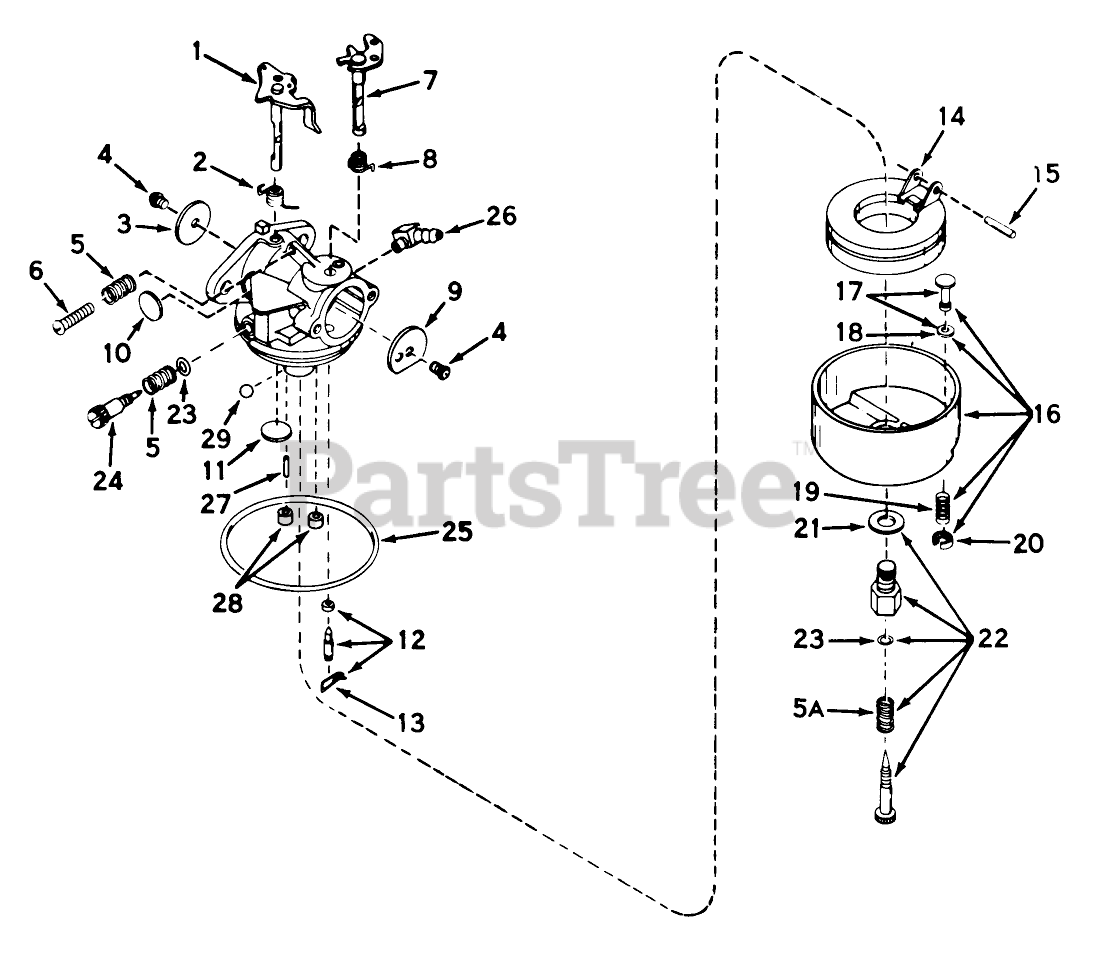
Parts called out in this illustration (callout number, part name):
1	Shaft/Lever-Throttle
2	Spring, Return
3	Shutter-Throttle
4	Screw-Shutter
5	Spring-Tension
5A	Spring
6	Screw-Throttle Crack Screw / Idle Speed
7	Shaft Lever Assy., Choke
8	Spring, Choke return
9	Shutter-Choke
10	Plug-Welch, Idle Mixture Well
11	Plug-Welch, Atmospheric Vent
12	Inlet Needle, Seat Clip Assy. (Incl. No. 13)
13	Clip-Spring
14	Float,Carburetor
15	Shaft-Float
16	Bowl Drain Assy., Float (Incl. No. 17)
17	Plunger Assy., Drain (Incl. Ref. 18)
18	Gasket-Plunger, Drain
19	Spring, Drain Plunger
20	Retainer, Plunger Spring
21	Washer-Bowl Nut
22	Adjustment Screw Assy., Main (Incl. Nos. 5A, 21 23)
23	ORing
24	Screw, Idle Adj.
25	O Ring-Bowl, Float
26	Fitting, Fuel Inlet
28	Plug, Cup
29	BalI, Steel
31	Repair Kit
